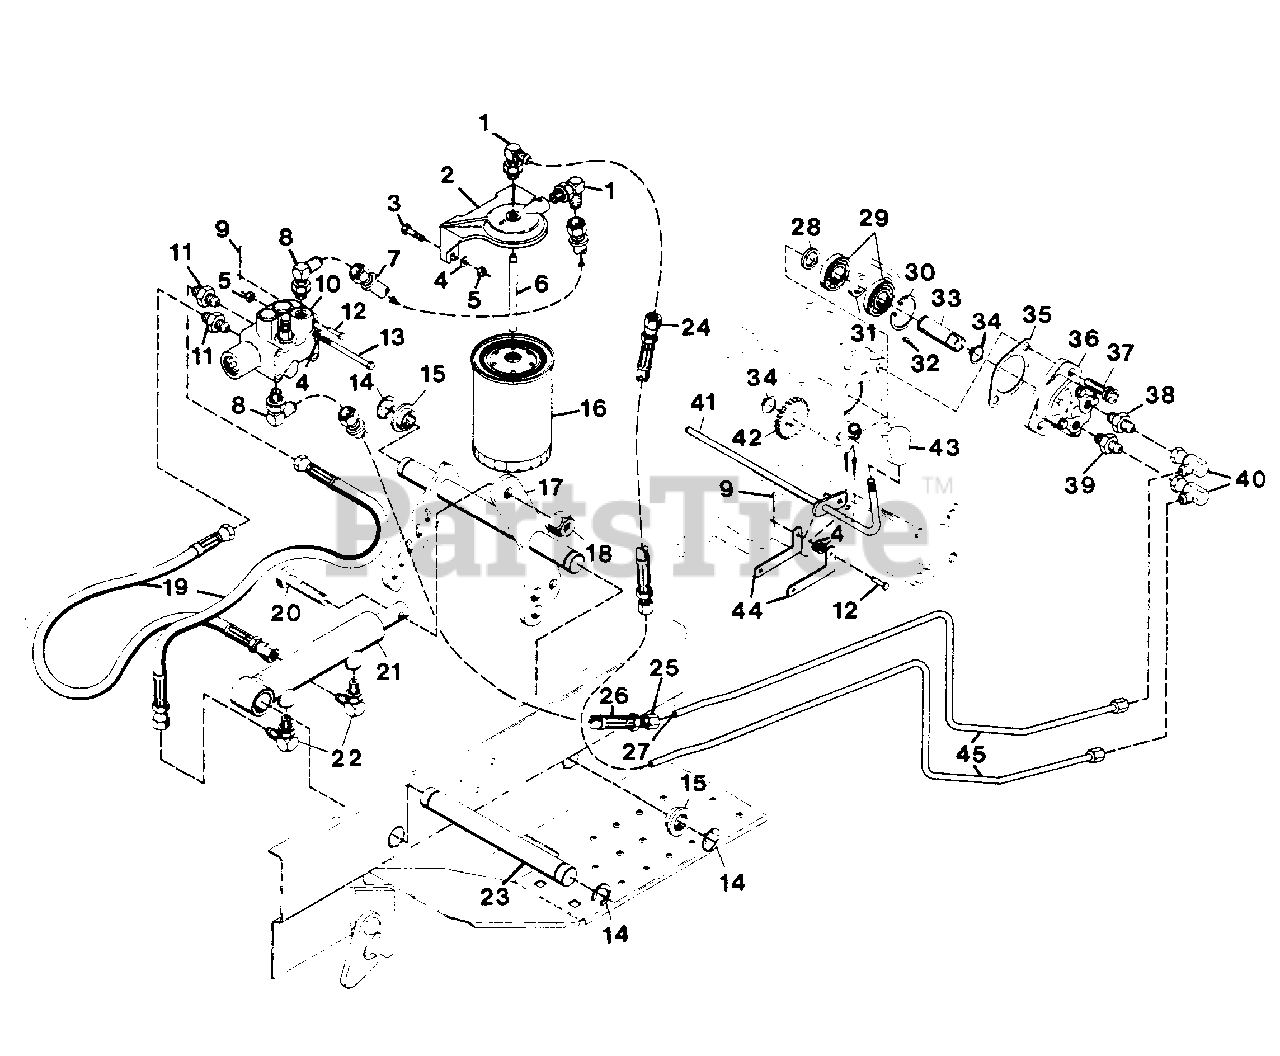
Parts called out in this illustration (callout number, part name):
1	ADAPTER
2	BRACKET, OIL FILTER
3	BOLT, HEX 1/4-20X1.00
4	WASHER, FLAT .281X.625X.065
5	NUT, LOCK 1/4-20
6	TUBE, OIL PICK-UP
7	HOSE, HYDRAULIC VALVE TO TANK
8	ADAPTOR(P-H #2503-6-6)
9	PIN, COTTER .094X.75
10	VALVE, HYDRAULIC
11	ADAPTOR(P-H #0503-4-4)
12	PIN, CLEVIS
13	BOLT, HEX 1/4-20X2.75
14	E-RING, 1.000 SHAFT
15	BUSHING, PIVOT
16	FILTER, SPIN-ON
17	WELDMENT, LIFT LEVER SHAFT
18	NUT, LOCK 1/2-13
19	HOSE, HYDRAULIC 14.5
20	BOLT, HEX 1/2-13X2.00
21	CYLINDER, HYDRAULIC
22	ADAPTOR(P-H #2503-4-4)
23	SHAFT, HYDRAULIC CYLINDER
24	HOSE, HYDRAULIC
25	NUT, FEMALE FLARELESS
26	HOSE, HYDRAULIC PUMP TO VALVE
27	SLEEVE, FEMALE FLARELESS
28	SPACER, .620X.750X.276
29	BEARING, BALL .590X1.378X.433
30	RING, RETAINING 1.378 BORE
31	SPACER, .620X.750X.364
32	KEY, WOODRUFF .125X.375 HARD
33	SHAFT, HYDRAULIC PUMP
34	RING, RETAINING .594 SHAFT
35	GASKET, COVER PLATE
36	PUMP, HYDRAULIC
37	SCREW, CAP 3/8-16 HEX SOCKET HD
38	ADAPTOR
39	ADAPTOR(P-H #0503-10-6)
40	ADAPTOR(P-H #3903-6-6)
41	WELDMENT, HYDRAULIC CONTROL ROD
42	GEAR, HYDRAULIC PUMP
43	KNOB, PTO
44	ROD, HYDRAULIC CONTROL
45	LINE, HYDRAULIC IN
